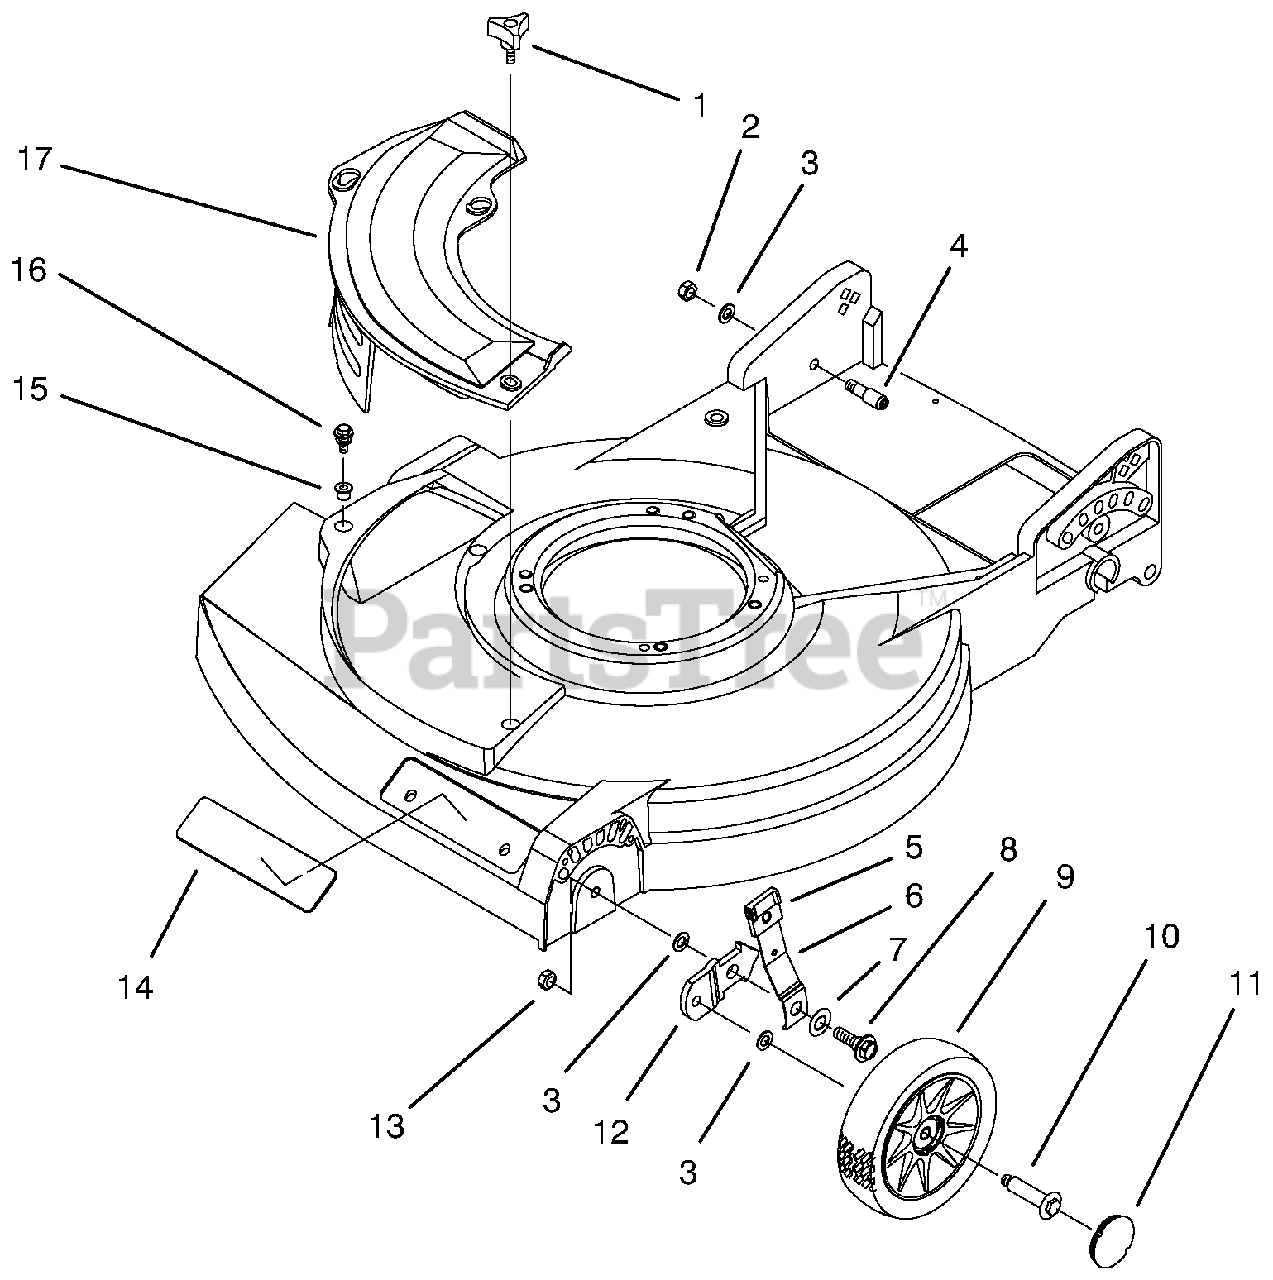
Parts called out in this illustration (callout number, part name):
1	Knob-Cover Plate
2	Nut-Lock
4	Bolt-Shoulder
5	Knob-Height Adjust
6	Spring Arm Ass'y-Front
7	Washer-Belleville
8	Bolt-Shoulder
9	Wheel & Tire Assembly 6"
10	Bolt-Shoulder
12	Bracket-Wheel Height Adj.
13	Nut-Lock
14	Housing-Applique
15	Grommet
16	Screw-Sems Thr'd Form.
17	Plate-Mulch
